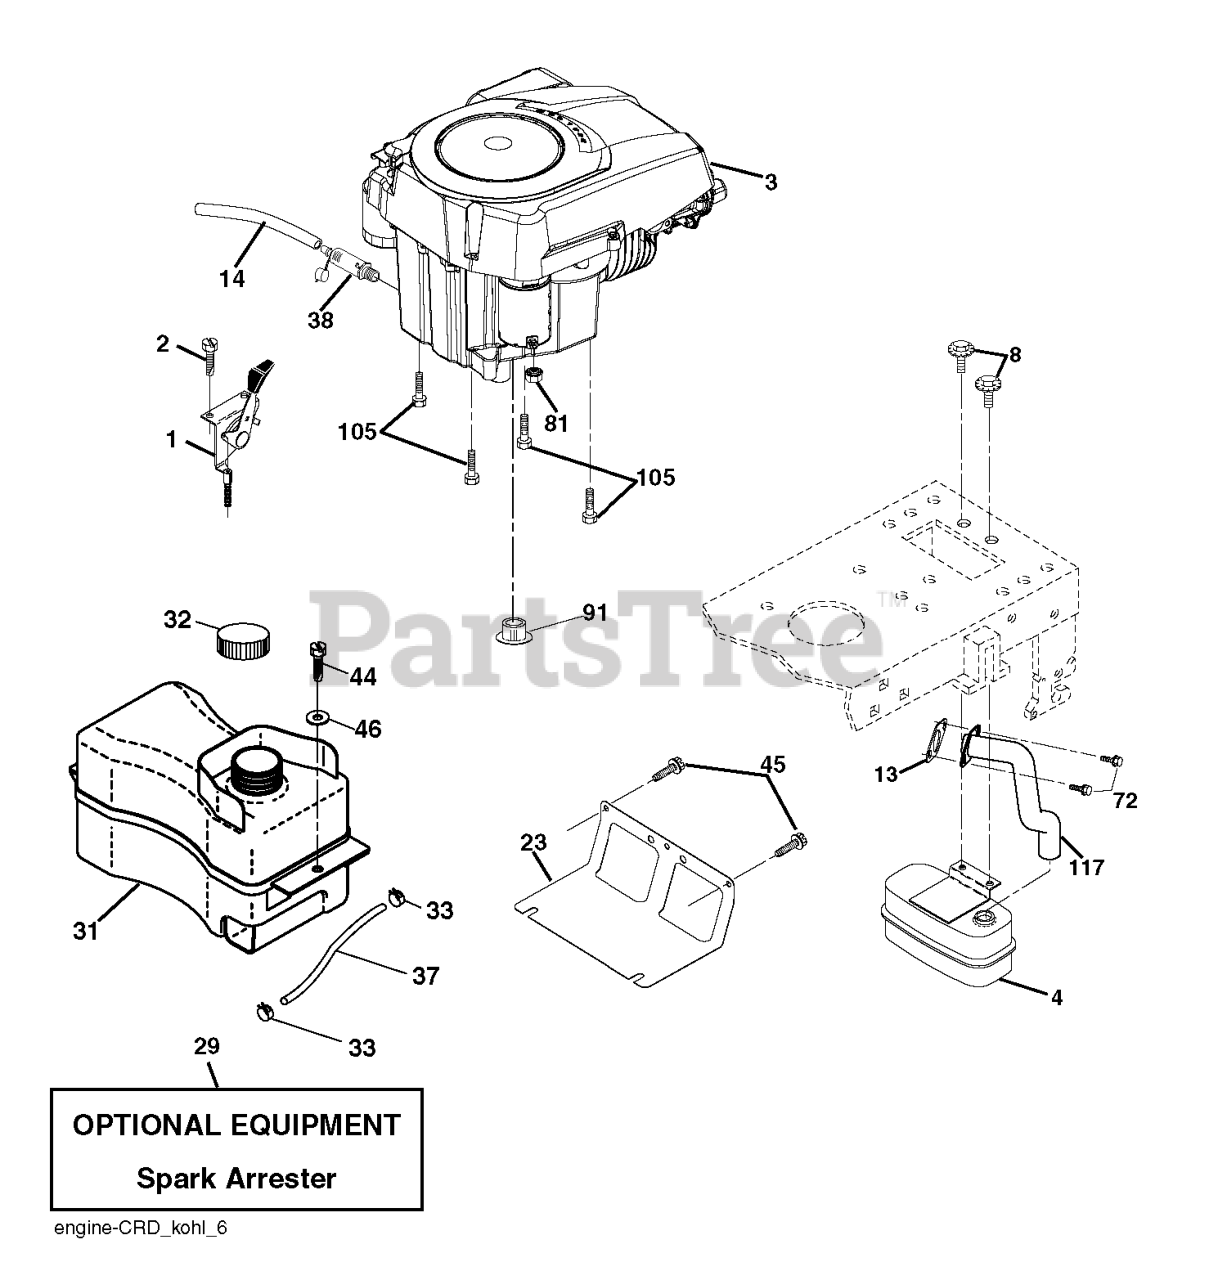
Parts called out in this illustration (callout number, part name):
1	CONTROL.TH/CK.C.
2	SCREW.#10 X 0.750.BOS
4	MUFFLER.SINGLE.CYL.KOHL/B&S
8	BOLT.5/16-18UNCX3/4 W/SEMS.BLK
13	GASKET.EXHAUST.KOHLER
14	TUBE, DRAIN OIL ASM.
23	SHIELD.BROWNING.DBR.GUARD
29	KIT.SPARK ARRESTOR 794945 B&S
31	RP TANK FUEL FRT 1.5 GAL
32	FUEL CAP
33	HOSE CLAMP
37	LINE.FUEL.20
38	PLUG DRAIN OIL EASY
44	SCREW HEXWSHR 1/4-20X3/4
45	SCREW, 3/8-16X3/4
72	SCREW.SOCKET HD.5/16-1
81	NUT
91	BUSHING.1.375OD
105	SCREW 3/8-16X1
117	RP.TUBE.EXHAUST.KOHL.COURAGE
